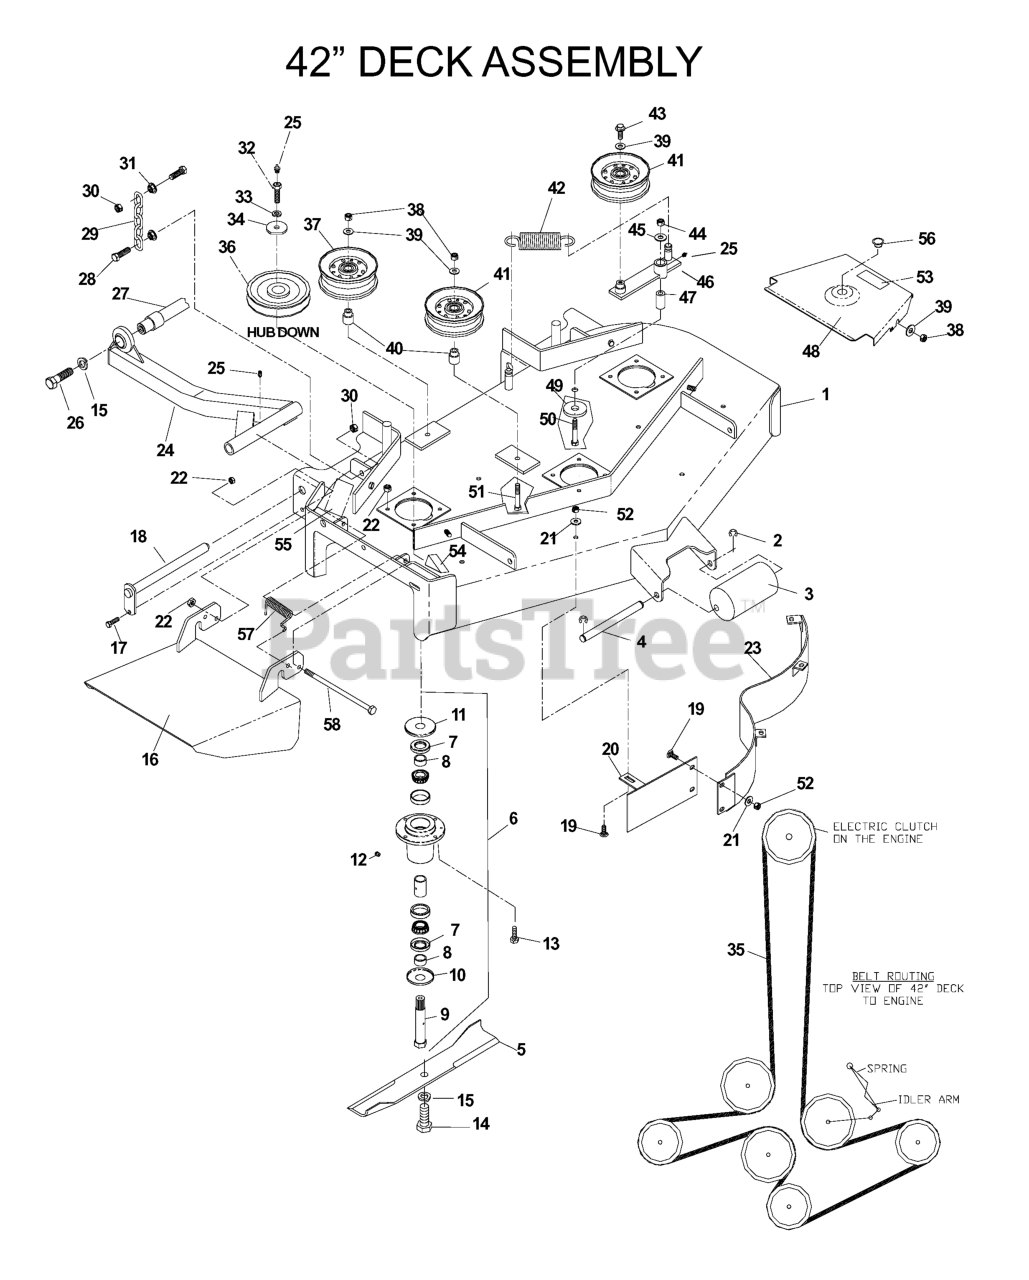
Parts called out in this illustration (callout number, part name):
1	DECK W/DECALS 42"
2	E-RING 1/2 (2 2)
5	BLADE OEM, 14-7/8
6	SPINDLE
7	SHAFT SEAL
9	SPLINED SHAFT - 42/48"
10	BOTTOM DUST CAP
11	TOP DUST CAP
12	PLUG-VENTED
13	HCS 5/16C X 1 1/4
14	HCS 5/8F X 1 1/4
15	LOCKWASHER 5/8
16	DISCHARGE CHUTE 42"
17	HCS 5/16C X 3/4
19	CARRIAGE BOLT 5/16C X 5/8"
20	CENTER BAFFLE
21	WASHER 5/16 FLAT
22	NUT 5/16 NYLOC
23	MAIN BAFFLE
24	STRUT, RIGHT
25	ZERK
26	HCS 5/8C X 2 GR.5
27	STRUT MOUNT WELDMENT
28	HCS 7/16C X 1 1/2
29	LIFT CHAIN
30	NUT 7/16C CENTERLOCK
31	NUT 7/16C WHIZ
32	DRILLED BOLT 7/16-20 X 1 1/2"
33	WASHER 7/16 LOCK
34	SPINDLE WASHER
35	BELT, DECK 42"
36	RP PULLEY - 42/48"
37	IDLER PULLEY (TALL)
38	NUT 3/8-16 NYLOC
39	WASHER 3/8 FLAT
40	IDLER BUSHING
41	IDLER PULLEY
43	4CS 3/8C X 1 SERRATED HEAD
44	NUT 1/2-13 HEX NYLOC ZD
45	WASHER 1/2 FLAT
47	PIVOT BUSHING
48	LT 42 CE SHIELD
49	WASHER, SUPPORT
50	HCS 1/2C X 3 1/4
51	SCREW 3/8C X 2 3/4 HEX CAP
52	NUT 5/16C CENTERLOCK
53	DECAL, NO STEP
54	DECAL, CPSC
55	DECAL, DANGER
56	PLUG, BUTTON HOLE
57	SPRING, TORTION
58	HCS 5/16-18 X 11 GR 5 ZD
539108351	STRUT, LEFT
539108937	RT 42 CE SHIELD
